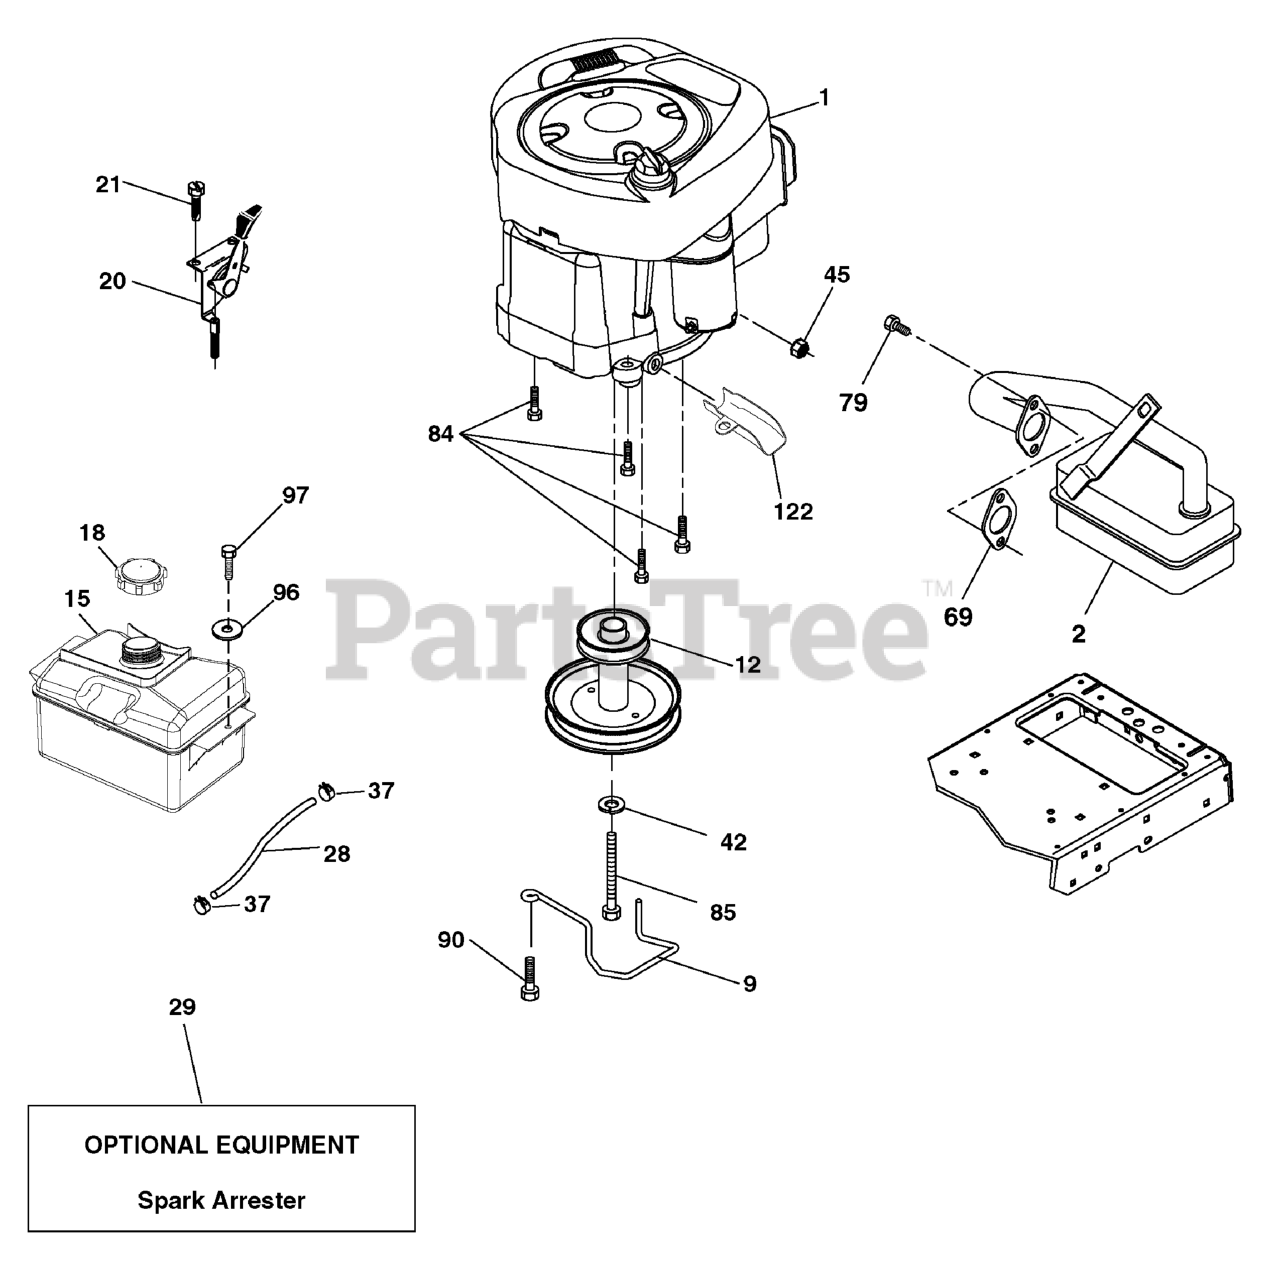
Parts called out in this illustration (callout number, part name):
1	* Engine, Briggs & Stratton
2	Muffler
9	Keeper Belt Engine
12	Pulley Engine
15	Tank Fuel 1.50
18	Cap Asm
20	Control Throttle/Choke
21	Screw #10 x 0.750
28	Fuel Line
29	Spark Arrester Kit
37	Clamp Hose
42	Washer Lock 7/16
45	Nut Keps Hex 1/4-20 unc
69	Gasket
79	Screw Socket Hd 5/16-18 x .75
84	Screw 3/8-16 x 1-1/4
85	Bolt Hex 7/16-20 x 4 x Gr. 5-1.5
90	Screw 3/8-16 x 1.0
96	Washer 9/32 x 7/8 x 16 Ga.
97	Screw 1/4-20 x 3/4
122	Extension Drain Oil
